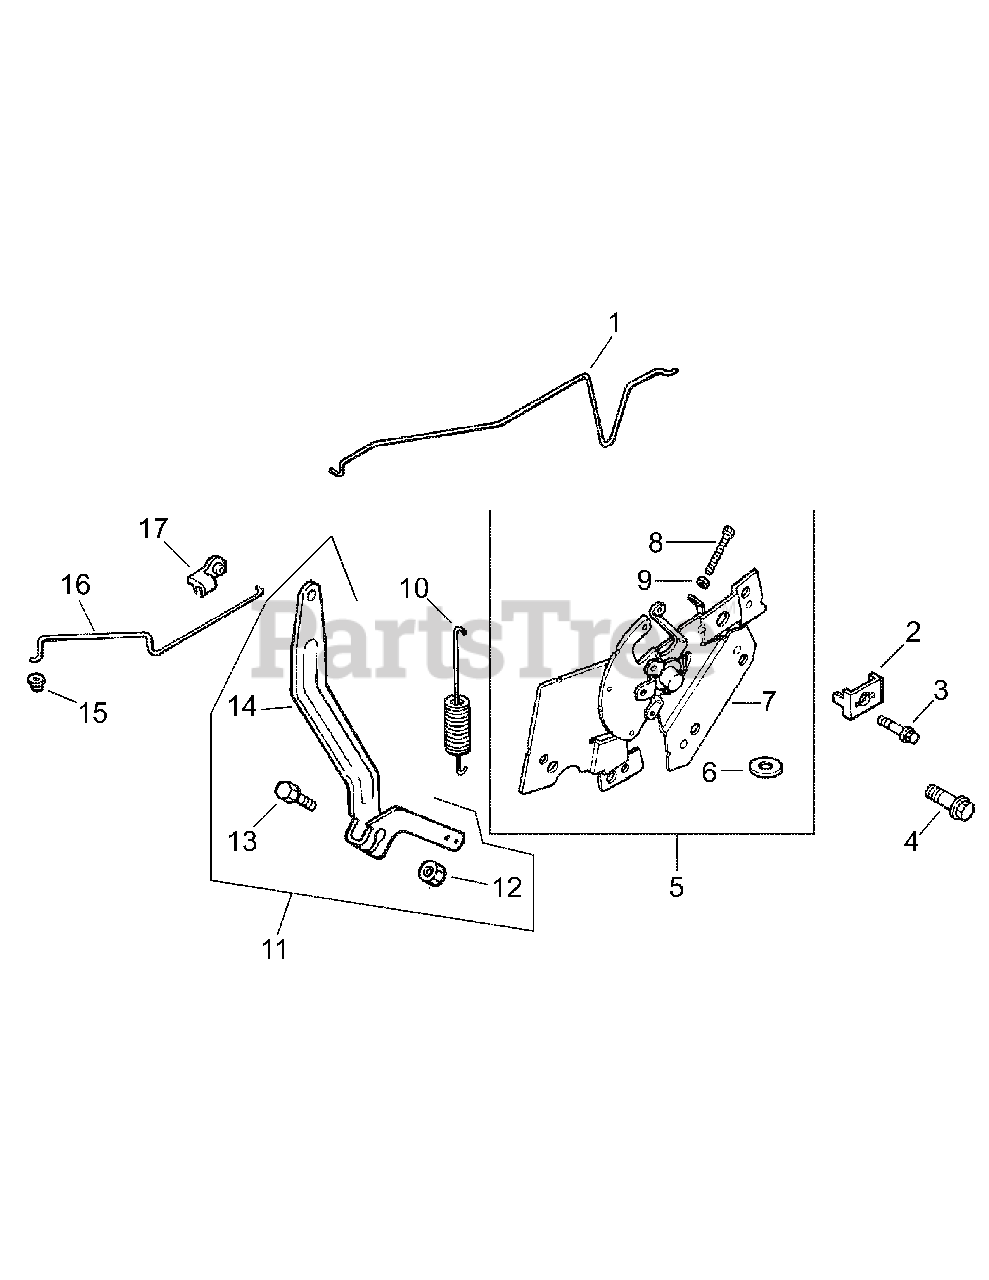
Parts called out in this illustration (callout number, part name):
1	Linkage, Choke
2	Clamp, Cable
3	Screw, Hex. Flange M5 x 0.8 x 16
4	Screw, Lobed Socket M6 x 1.0 x 20
5	Control, Speed Assembly (Incl. 6-9)
6	Spacer, Shim .005
7	Bracket, Control
8	Screw, Hex. Flange M4 x 0.7 x 30
9	Nut, Hex. M4 x 0.7
10	Spring, Governor
11	Kit, Governor Lever (Includes 12-14)
12	Nut, Hex. Flange M6 x 1.0
13	Screw, Hex. Flange M6 x 1.0 x 25
14	Lever, Governor
15	Bushing, Linkage Retaining
16	Linkage, Throttle
17	Bushing, Linkage Retaining
